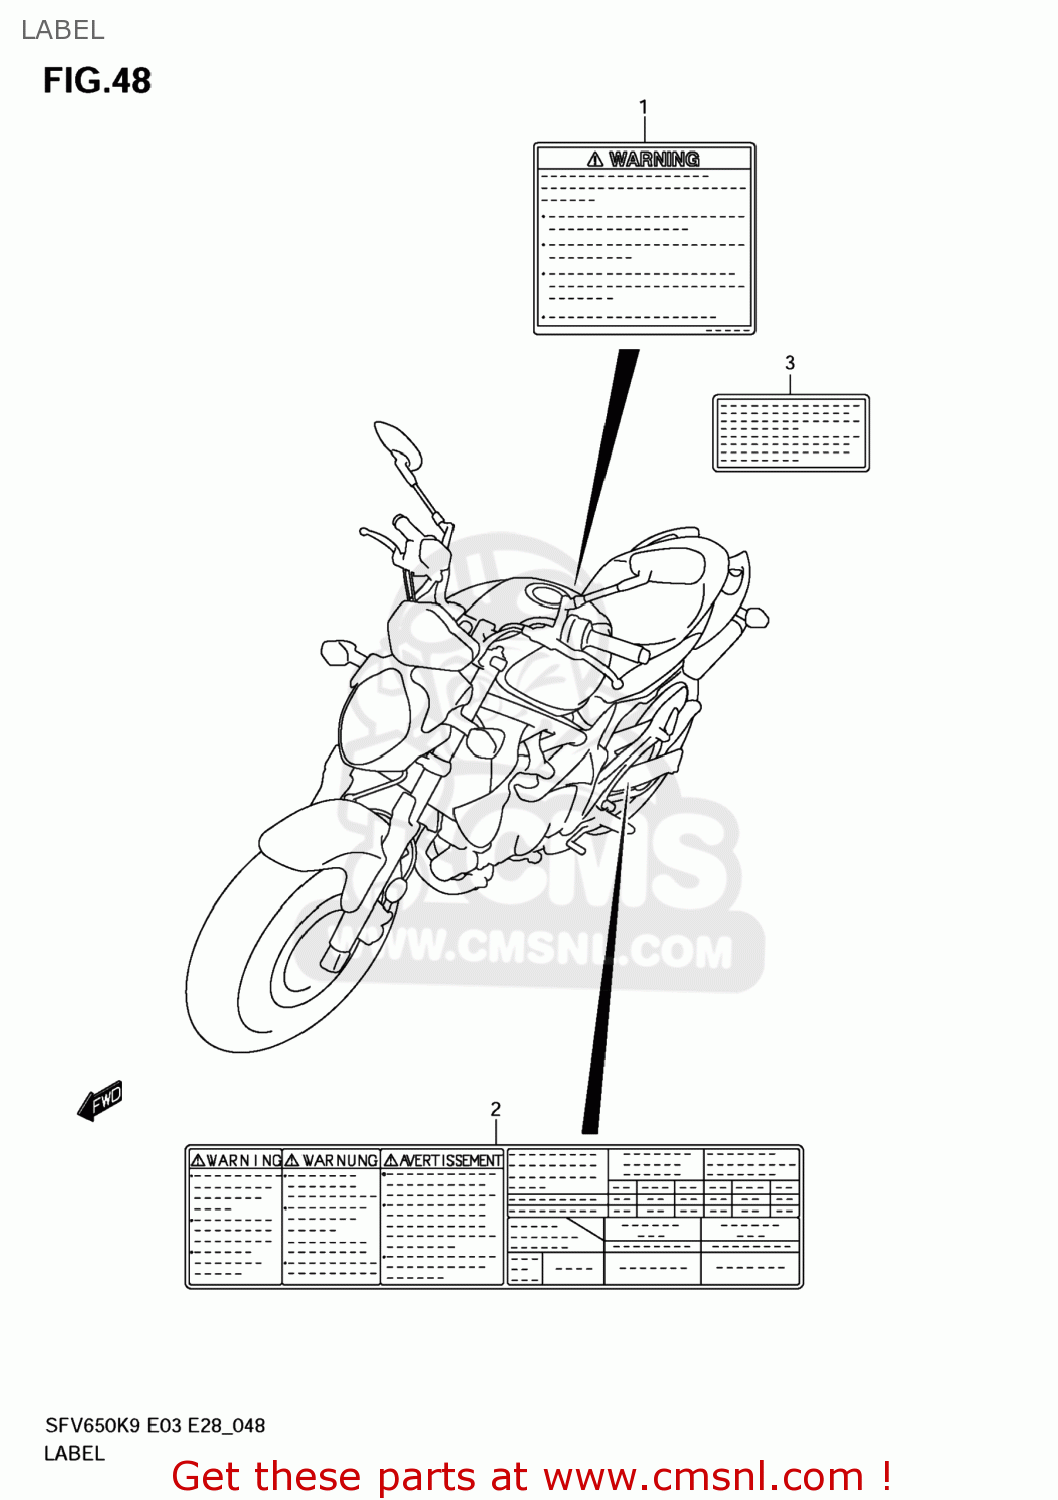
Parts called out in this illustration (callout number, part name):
1	LABEL,GENERAL WARNING
2	LABEL,TIRE INFORMATION
3	LABEL,MANUAL NOTICE
4	MANUAL,OWNER'S
